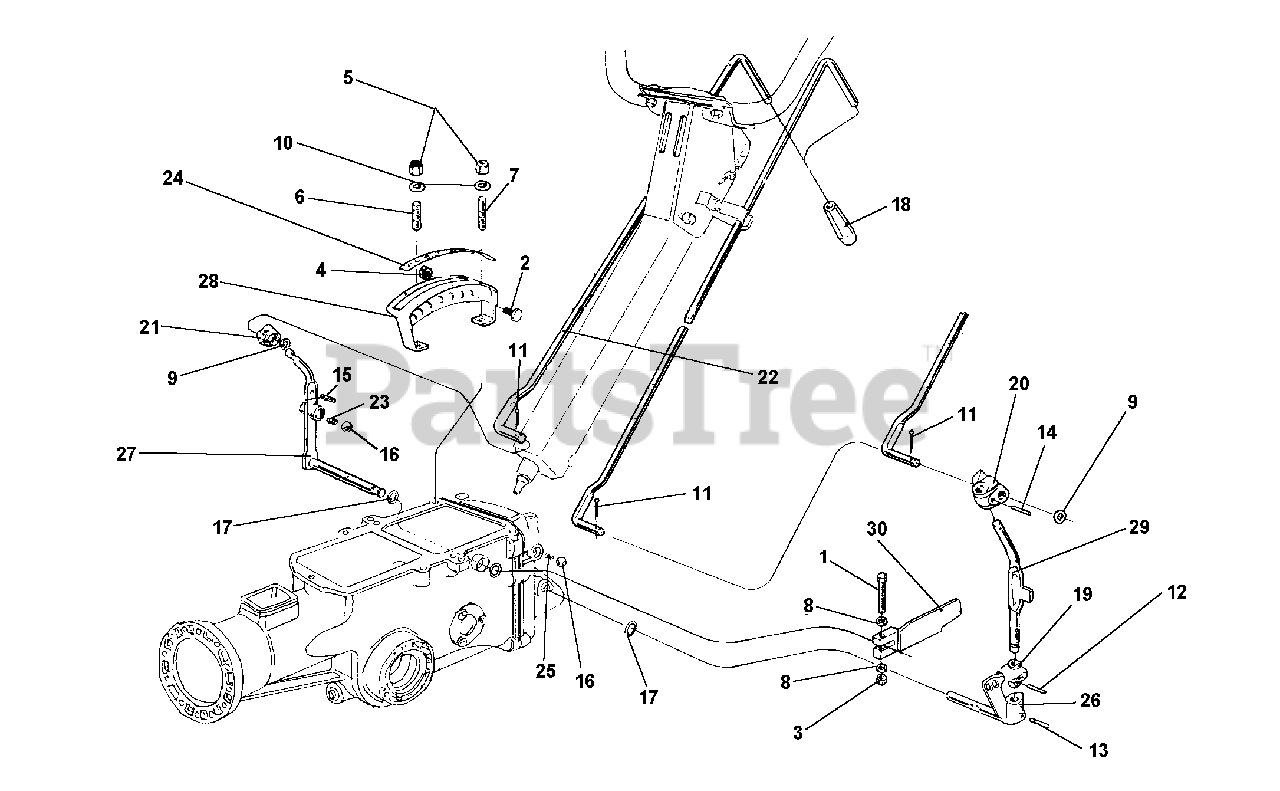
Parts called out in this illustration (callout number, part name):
1	SCREW M6 X 40
2	SCREW M8 X 14
3	NUT, SELF LOCKING M6
4	NUT, SELF LOCKING M8
6	STUD M8 X 38 X 14 X 20
7	STUD M8 X 46 X 16 X 16
8	FLAT WASHER 6.4
9	WASHER P10.5 X 18
10	SUPER WASHER 8 DIN 6796
12	LOCKING PIN 4 X 20 SPIRAL
14	LOCKING PIN 4 X 24 SPIRAL
15	LOCKING PIN SPIRAL
16	BALL 15/32 RIV RB-11.906
17	O-RING 115 11.91 X 2.62
19	PTO STOP RING
20	PTO ARTICULATION
22	ROD, SPEED CONTROL 745
24	SPEED DECAL, 725, 735, 745
26	PTO PIN, 745
27	GEARBOX LEVER
28	SPEED QUADRANT, 725, 735, 745
29	PTO CONTROL LEVER
30	PTO LOCKOUT, 745
